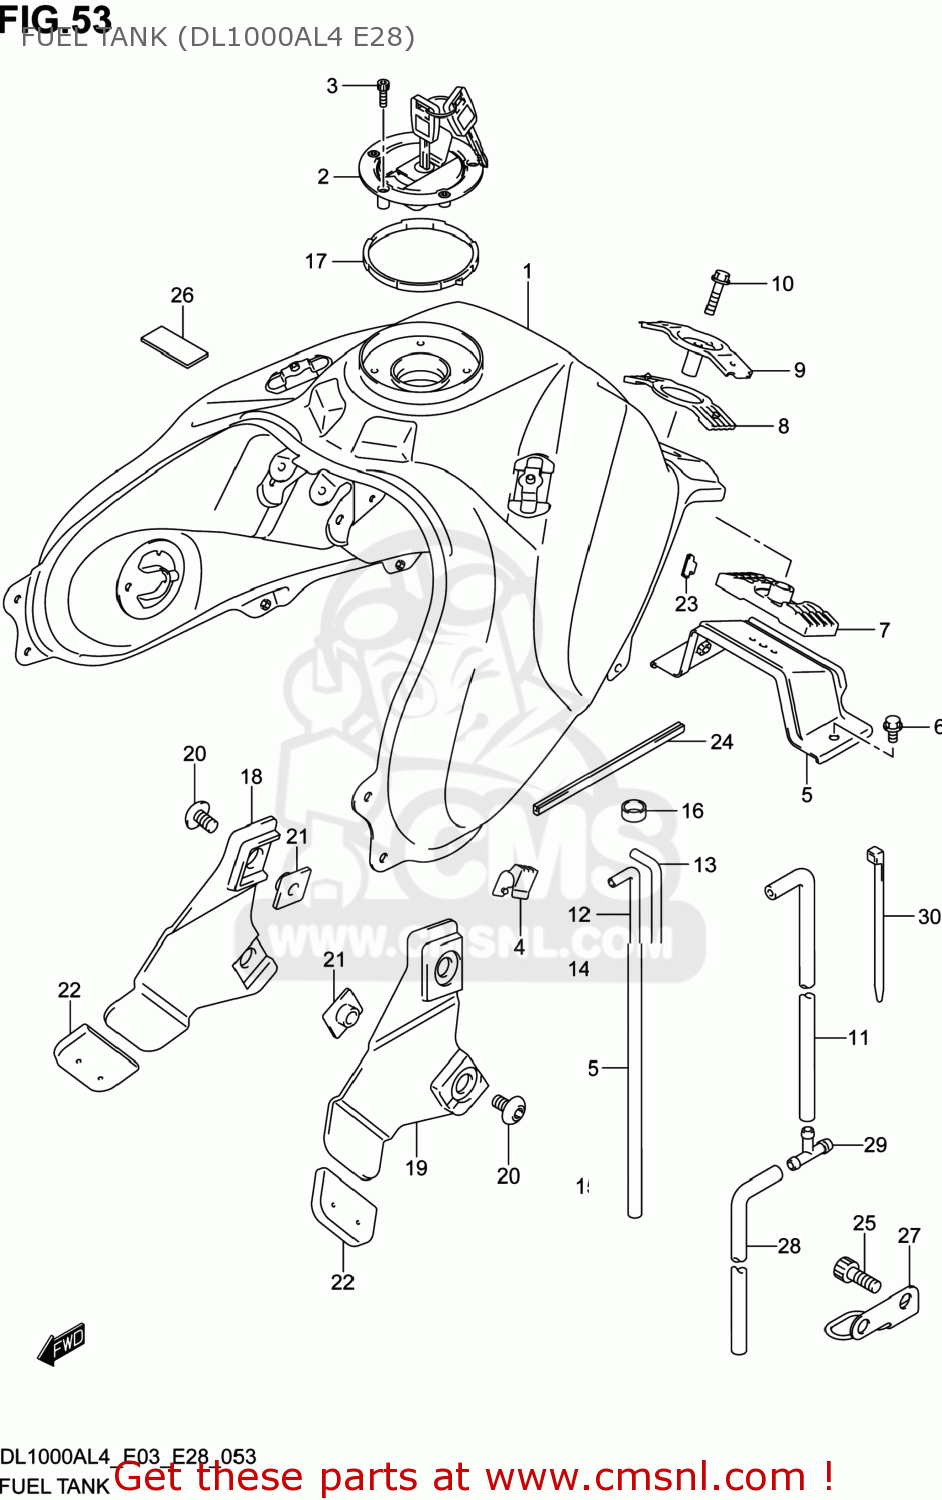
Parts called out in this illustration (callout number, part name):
1	TANK ASSY,FUEL(RED)
2	CAP SET,FUEL TANK
3	BOLT,FUEL TANK FILLER CAP
4	CUSHION,FUEL TANK SIDE
5	BRACKET,FUEL TANK REAR
6	BOLT
7	CUSHION,FUEL TANK RR LWR
8	CUSHION,FUEL TANK RR UPR
9	BRACKET,FUEL TANK RR UP
10	BOLT
11	HOSE,FUEL TANK WATER DRAIN
12	HOSE,FUEL TANK BRTHR NO.1
13	HOSE,TANK BREATHER NO.2
14	3 WAY
15	HOSE,FUEL TANK BRTHR NO.2
16	HOSE(12X16X600)
17	MOLDING,FUEL TANK COVER
18	BRACKET,FUEL TANK COVER SIDE,R
19	BRACKET,FUEL TANK COVER SIDE,L
20	SCREW(6X10)
21	NUT(M6)
22	CUSHION,FUEL TANK COVER BRKT
23	CUSHION,FUEL TANK COVER
24	MOLDING,FUEL TANK RR
25	BOLT
26	CUSHION,FUEL TANK
27	GUIDE,DRAIN HOSE
28	HOSE,FUEL TANK DRAIN NO.2
29	3 WAY
30	CLAMP(L:145)
